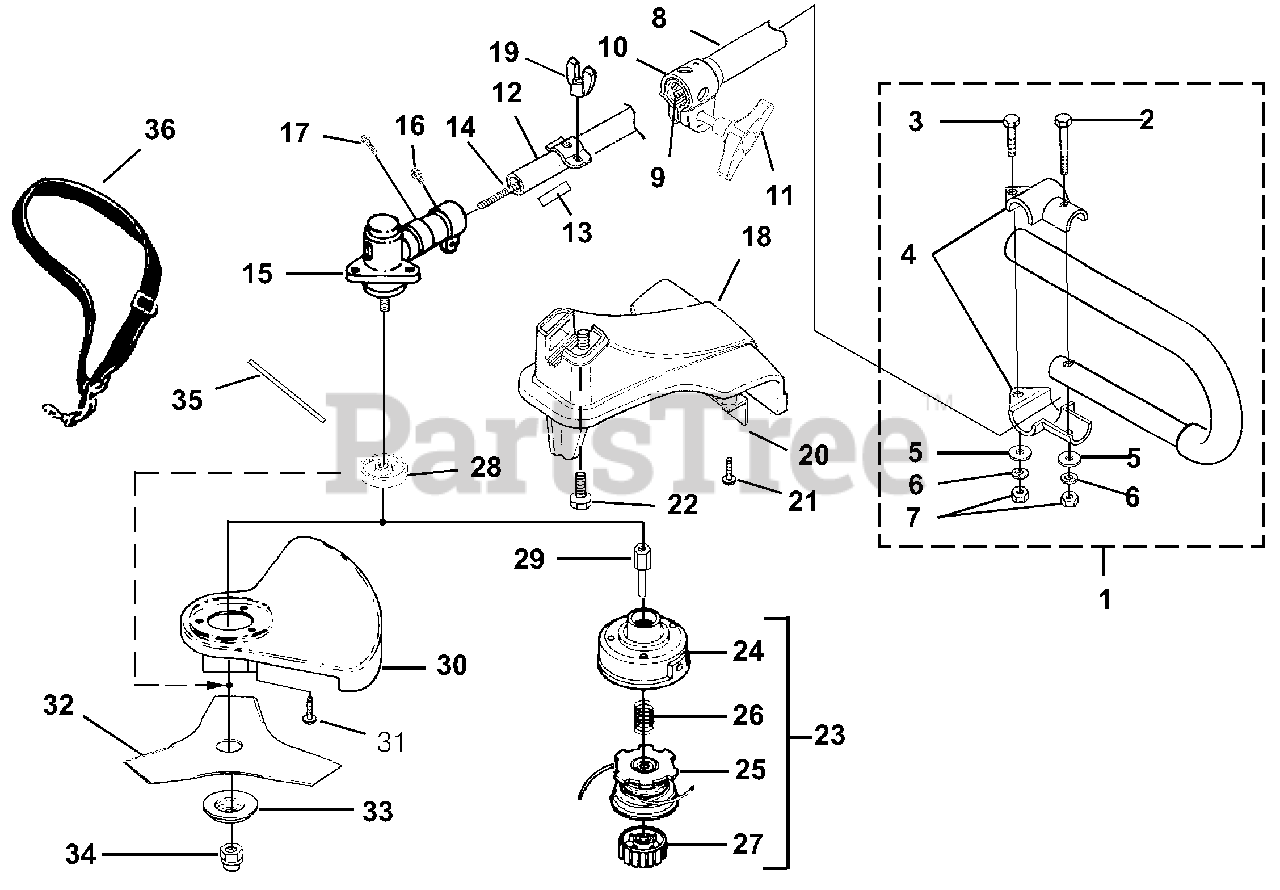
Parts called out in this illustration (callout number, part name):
1	HANDLE("J")
2	SCREW-Hex Hd. (1/4-20 X 1 1/2")
3	SCREW-Hex Hd. (1/4-20 X 1")
4	CLAMP-Handle Bar
5	WASHER-Flat (1/4")
6	WASHER-Lock (1/4")
7	NUT-Hex (1/4-20)
8	DRIVESHAFT HOUSING (Upper)
9	FLEXSHAFT-w/Collar & Liner
10	COUPLER KIT
11	KNOB
12	DRIVESHAFT HOUSING (Lower)
13	DECAL-Warning
14	SHAFT-Flexible
15	GEAR HEAD
16	Screw, Cap Hd. (1/4-20 X 7/8")
17	Screw-Hex Hd. (10-24 x 1/2")
18	GRASS DEFLECTOR KIT
19	WING NUT
20	BLADE-Cut-Off
21	SCREW, Thread Form. (10-24 X 3/4")
22	SCREW-Square Head
23	STRINGHEAD-Complete (.080")
24	HOUSING & EYELET (Dual Line)
25	SPOOL & STRING (.080")
26	SPRING-Compression
27	RETAINER-Spool (L.H. Thread, Red)
28	WASHER-Flanged
29	ADAPTER-Shaft
30	BLADE GUARD
31	SCREW
32	BLADE-Tri-Arc(TM)
33	WASHER-Cupped (Lower)
34	NUT-Hex (L.H.)
35	TOOL-Holding Pin
36	HARNESS
